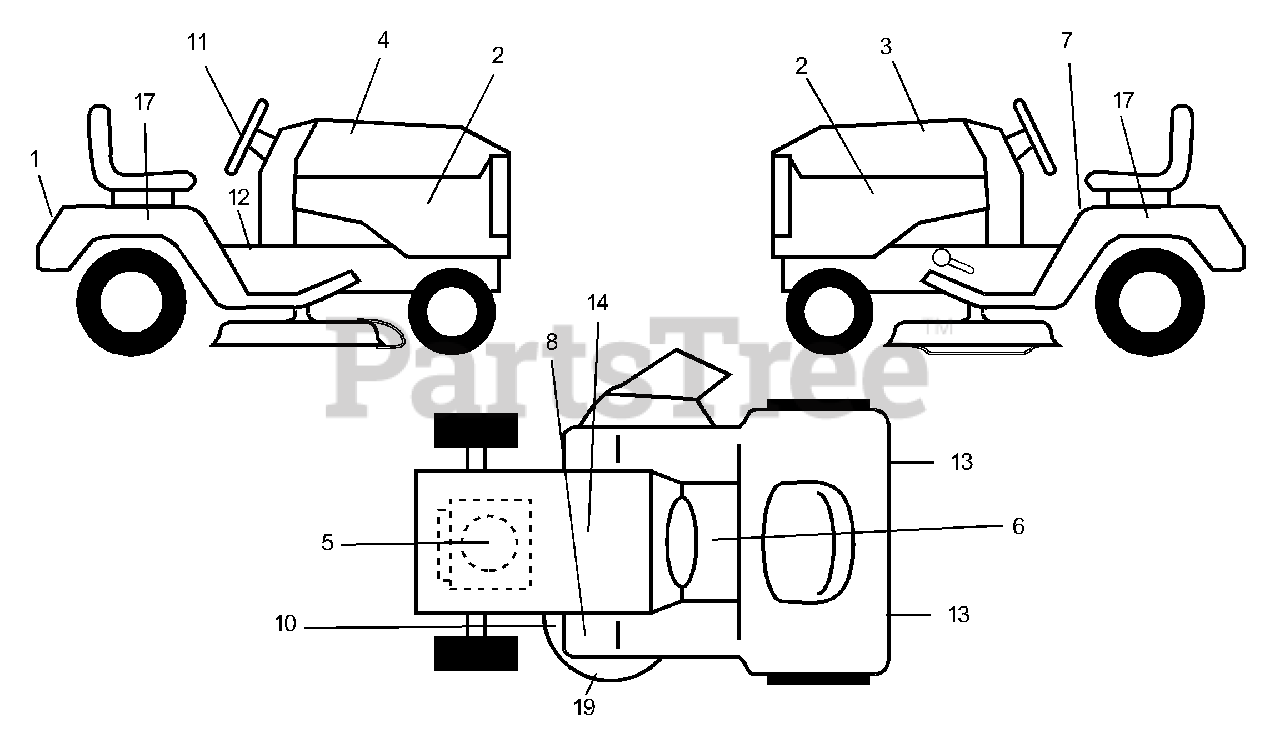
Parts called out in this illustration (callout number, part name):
1	Decal Fender
2	Decal Side Panel
3	Decal Hood LH
4	Decal Hood RH
5	Decal HP Engine
6	Decal Parking Brake
7	Decal Danger Fender English
8	Decal Clutch/brake English
10	Decal V-Belt Sch
11	Decal Steering
12	Decal Oper s DL Eng
13	Reflector Taillight
14	Decal, Btry Dngr/Psn
17	Decal Fender Side
